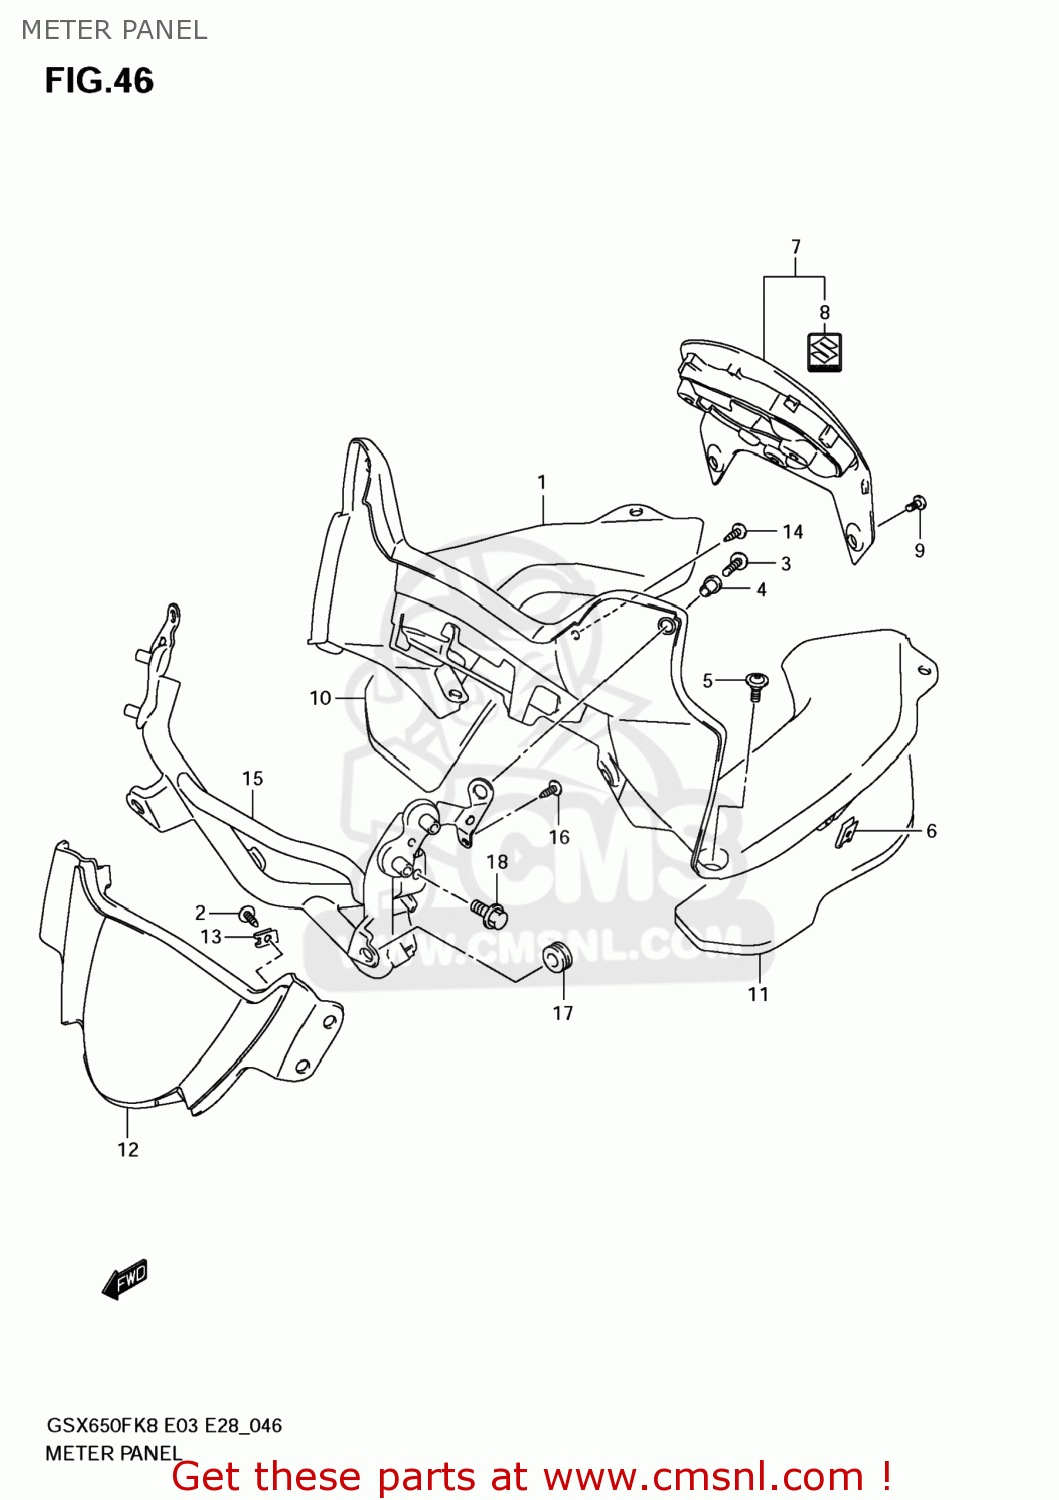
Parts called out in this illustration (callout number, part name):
1	PANEL,METER
2	SCREW
3	SCREW
4	NUT
5	BOLT(5X13)
6	NUT
7	LID,METER PANEL
8	EMBLEM,S
9	SCREW(6X28)
10	CUSHION,PANEL,R
11	CUSHION,PANEL,L
12	PANEL,METER FR
13	NUT
14	SCREW
15	BRACE,COWLING
16	SCREW
17	CUSHION
18	BOLT
